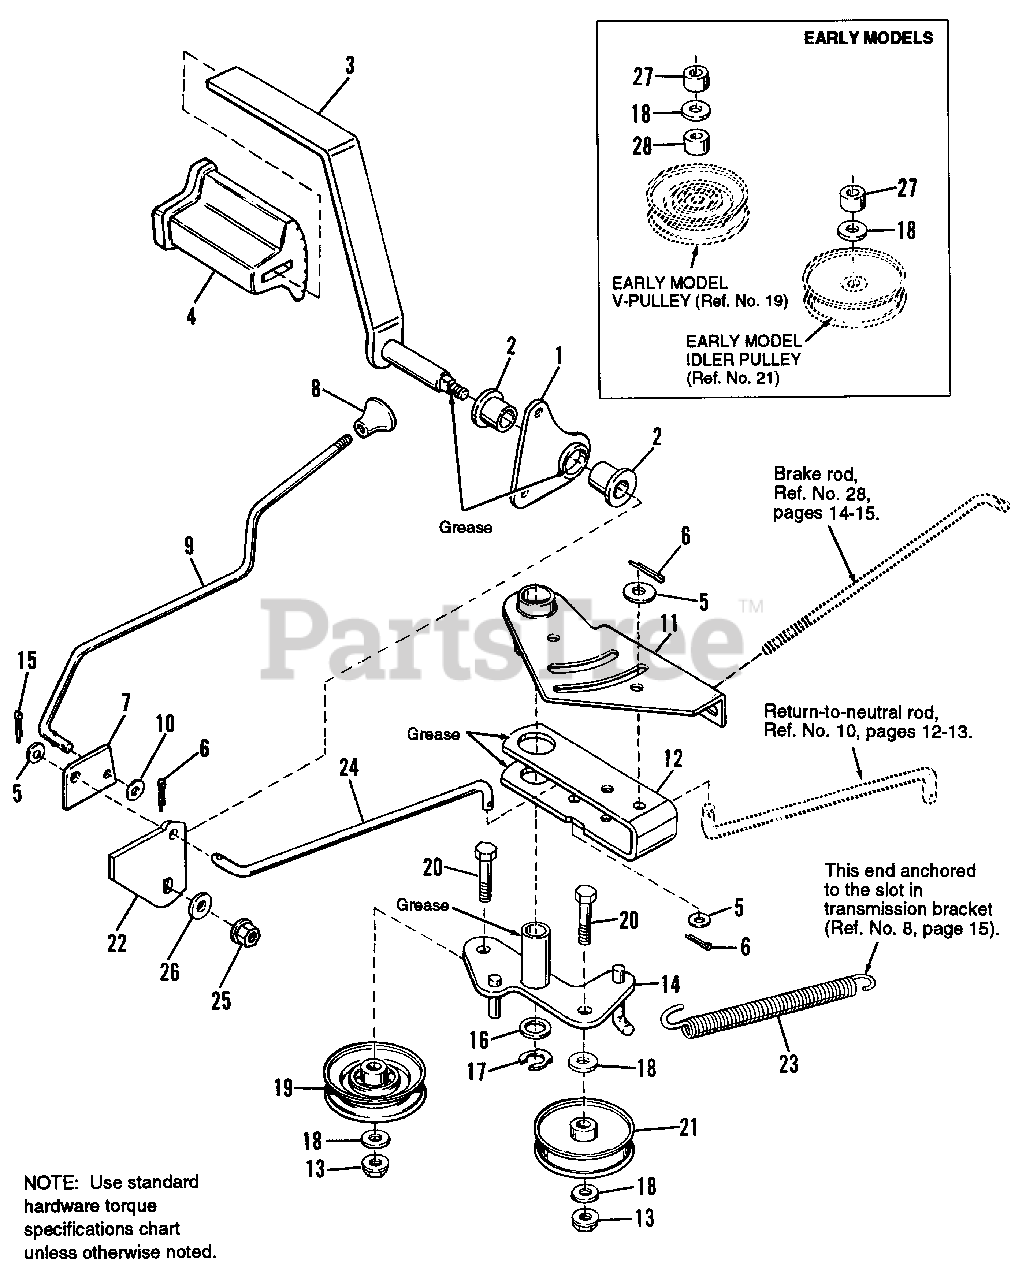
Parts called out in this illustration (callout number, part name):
2	BUSHING, Plastic
3	BRAKE PEDAL ASSY.
4	PAD, Foot Pedal
5	WASHER, Plain, 11/32
6	COTTER PIN
7	CAM, Parking Brake
8	KNOB, Plastic
9	ROD, Parking Brake
10	WASHER, Plain, 9/32
11	ACTUATOR ASSY.
12	LEVER, Clutch
13	NUT, Flange Whizlock, 3/8-16
14	PIVOT ASSY., Idler
15	COTTER PIN
16	WASHER, 5/8
17	KLIPRING, 5/8
18	WASHER, Plain, 13/32 (Qty. 4 on early models)
20	CAPSCREW, 3/8-16 x 1-3/4
21	PULLEY, Idler, Flat
22	ARM, Foot Pedal
23	SPRING, Drive
24	ROD, Clutch, 5/16 Dia.
25	NUT, Hex ESNA, 3/8-16
26	WASHER
27	SPACER (Early models only)
28	SPACER (Early models only)
